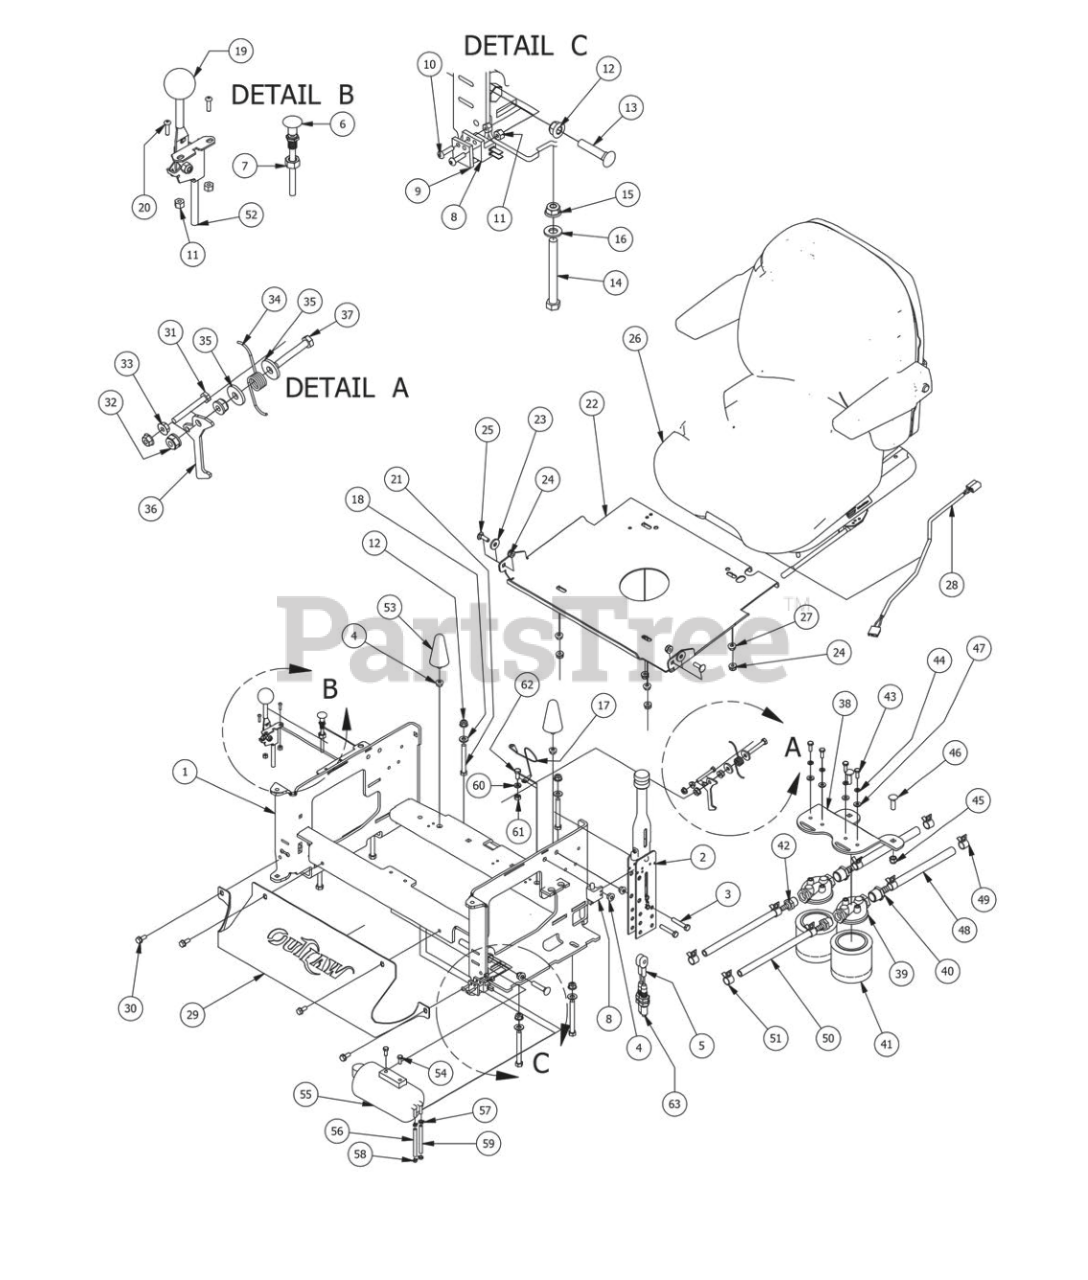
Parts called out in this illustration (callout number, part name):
1	Outlaw Seat Bracket 2012
2	Hand Brake
3	5/16" x 1 3/4" Hex Bolt
4	5/16" Nylon Flange Nut
5	Long Brake Cable
7	3/8" Fine Threaded Jam Nut
8	Safety Switch
9	Switch Block Plastic
10	10-24 x 1 BS C/S 18-8 SS
11	10-24 Nylon Insert Locknut
12	3/8" Nylock Flange Nut
13	3/8 x 1 3/4 Carriage Bolt
14	3/8-16x3-1/2 grade 5 hex bolt
15	3/8" Nylock Flange Nut
16	3/8" Flat Washer
17	Seat Cable
18	3/8" Flat Washer
19	Universal Throttle Head - 2012
20	10-24 X 5/8 BS C/S 18-8 SS
21	3/8-16x3 grade 5 hex bolt
22	2006 Seat Plate
23	.360 ID Plastic Washer
24	5/16-18 Nylon Flange Nut
25	5/16" x 1" Carriage Bolt
26	2010 Outlaw Seat
27	5/16" Flange Nut
28	Seat Switch Adapter
29	Outlaw Cooler Cover
30	5/16 x 3/4 washer head type F screw
31	1/4-20 x 2 Hex Bolt
32	5/16-18 Nylon Flange Nut
33	1/4-20 Hex Flange Nuts Zinc w/Serrations
34	Torsion Spring for Seat latch
35	.360 ID Plastic Washer
36	Seat Latch Lever
37	5/16-18 X 2 Hex C/S (GR.5) ZC
38	Outlaw Filter Bracket
39	Filter Head-Hydraulic Filter
40	Filter Head Fitting 1/2 x 1/2
41	Hydraulic filter
42	1/2" Pipe to 3/8" Barb
43	1/4" x 3/4" Hex Bolt
44	1/4" Lock Washer
45	3/8 Nylock Nut
46	3/8" x 1 1/4" Carriage Bolt
47	1/4" Flat Washer
48	1/2 Clear Braded Hose Priced/Foot
49	1/2 Hose Clamp
50	3/8 clear hose price per foot
51	3/8 hose clamp
52	Outlaw Throttle Cable Only
53	Rubber Cone-1621-153
54	M6-1.0 X 16MM Hex Bolt
55	Carbon Canister ZT,CZT,Outlaw
56	3/16 vinyl tubing
57	3/16 vinyl clamp
58	3/16" Vinyl Hose Clamp
59	1/4" vinyl tubing
60	5/16" Lock Washer
62	5/16" x 3/4" Hex Bolt
63	Short Brake Cable
